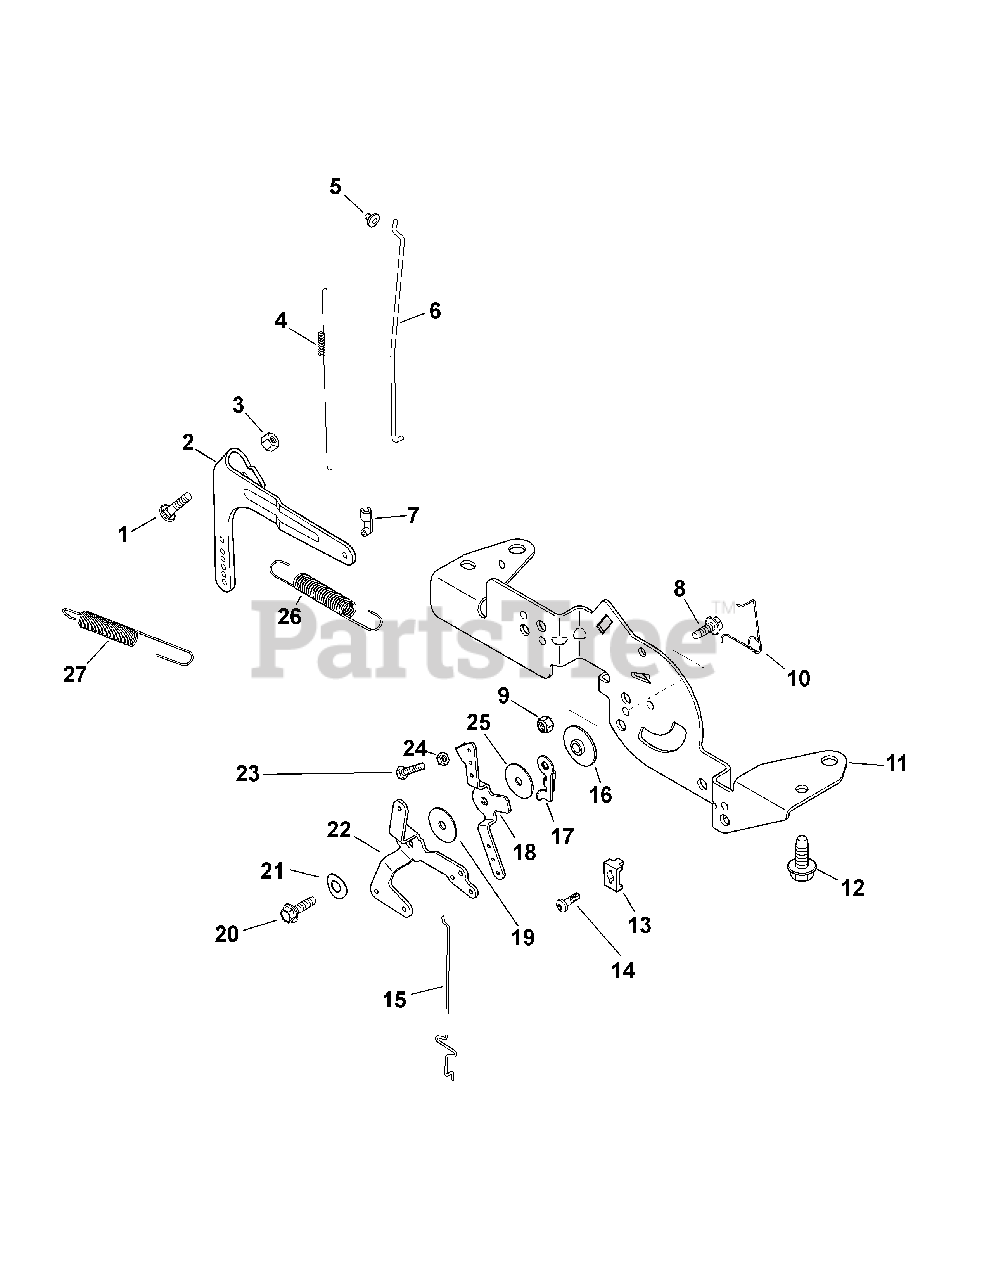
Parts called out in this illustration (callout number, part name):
1	Bolt, M6 x 1.0 x 25
2	Governor Lever
3	Flange Nut, M6 x 1.0
4	Linkage Spring
5	Linkage Retaining Bushing
6	Throttle Linkage
7	Throttle Linkage Bushing
8	Flange Screw, M5 x .8 x 16
9	Lock Nut, M5 x .8
10	Choke Return Spring
11	Control Bracket
12	Flange Screw, M6 x 1.0 x 16
13	Cable Clamp
14	Screw, M5 x .8 x 16
15	Choke Linkage
16	Control Assembly Spacer
17	Throttle Actuator Lever
18	Throttle Control Lever
19	Flat Washer, 5.5mm
20	Flange Screw, M5 x .8 x 20
21	Spring Washer, 1/4
23	Screw, M4 x .7 x 25
25	Flat Washer, 5mm
26	Governor Spring
27	Governor Spring
